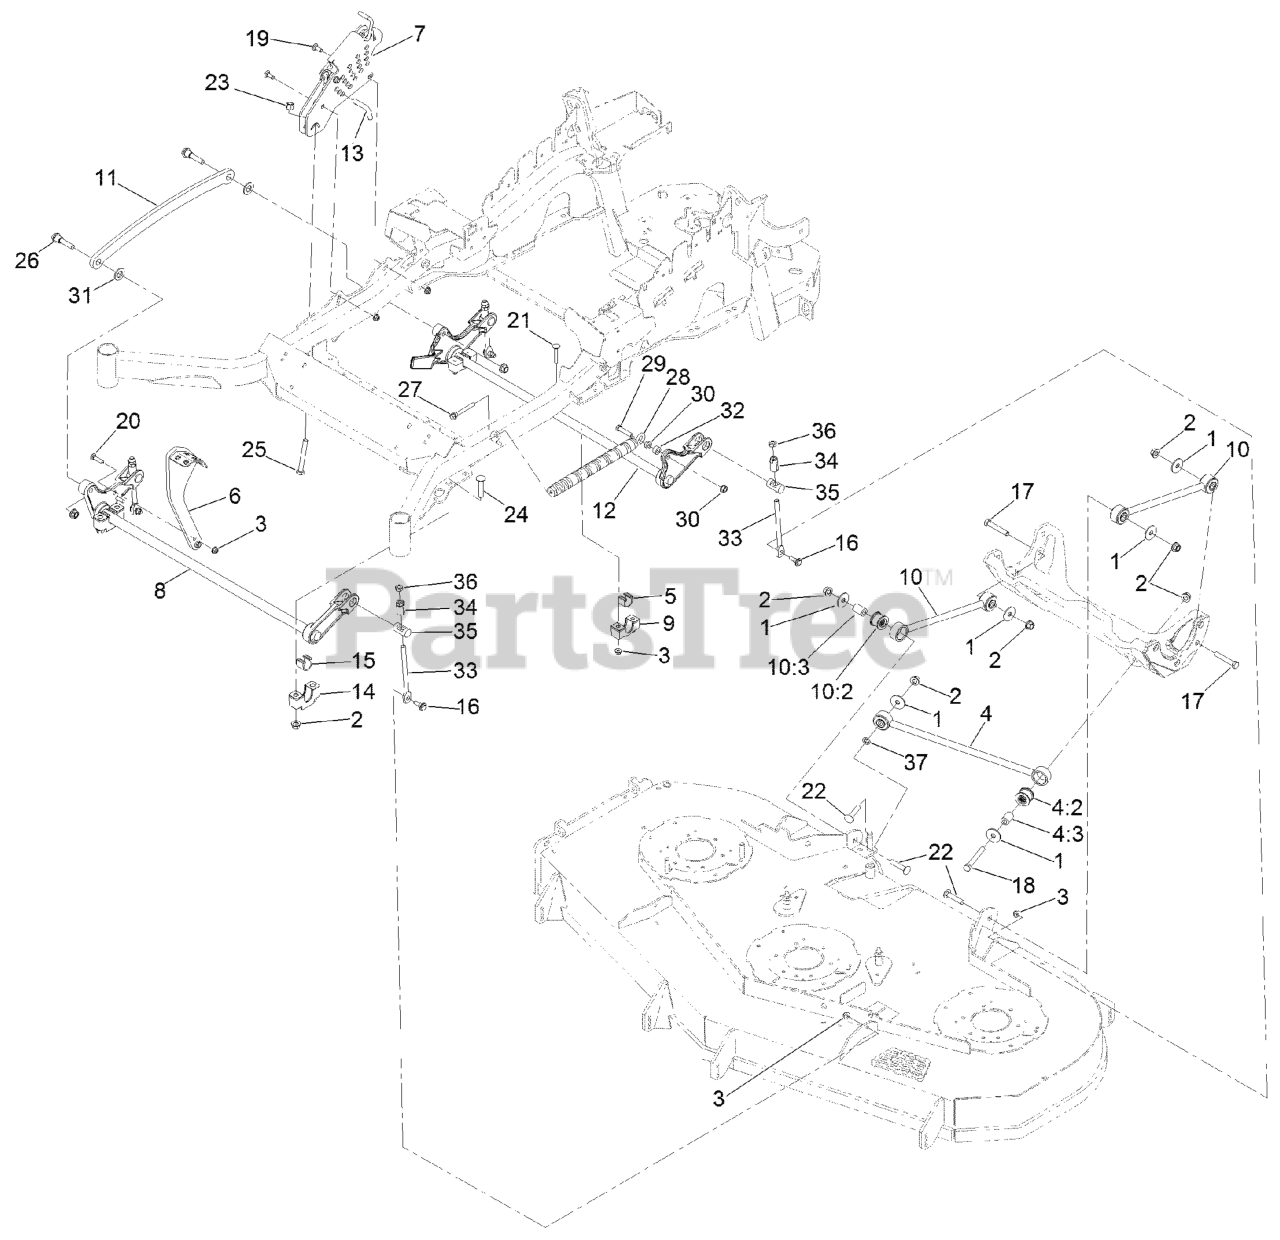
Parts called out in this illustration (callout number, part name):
1	WASHER-THRUST
2	Nut-Lock 1/2-13
3	NUT-HF, NI
4	PANHARD ROD ASM
4:2	BUSHING-SUSPENSION, RUBBER
5	BEARING-CROSS SHAFT, REAR
6	LEVER-FOOT
7	HOC ASM
8	DECKLIFT-FRONT
9	SUPPORT-CROSS SHAFT, BEARING REAR
10	DECK STRUT ASM
10:2	BUSHING-SUSPENSION, RUBBER
11	LINK-LIFT, DECK
12	LIFT-DECK, REAR
13	PIN-HOC
14	SUPPORT-CROSS SHAFT, BEARING
15	BEARING-CROSS SHAFT, FRON
16	SCREW-SHOULDER, HHF
17	SCREW-HH
18	SCREW-HH
19	BOLT-CARR
20	SCREW-CARR
21	Bolt-Carriage 3/8-16 X 2 1/4
22	SCREW-CARR
23	NUT-LOCK, NI
24	Bolt-Carriage 1/2-13 X 2 1/2 Spl Neck
25	BOLT-TAP
26	SCREW-HHF, SHOULDER
27	BOLT-SHOULDER
28	SPRING-EXTENSION
29	SCREW-HH
31	WASHER-FLAT
33	LINK-ADJUSTER, DECK LIFT
34	ADJUSTER-LIFT, DECK
35	TRUNNION
36	NUT-JAM
37	NUT-PUSH
